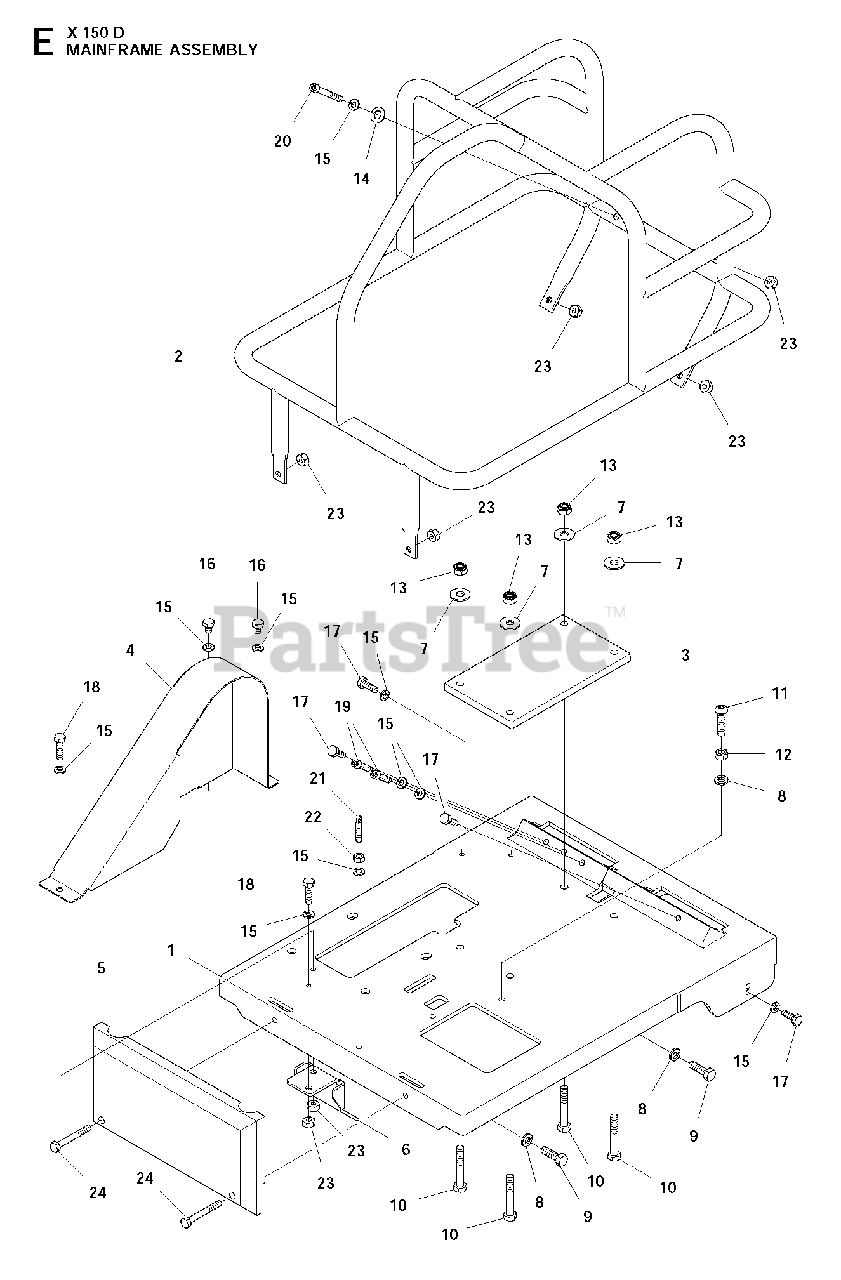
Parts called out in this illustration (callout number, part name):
7	FLAT WASH 5/16 USS ENGINE/BIG
9	HEX BOLT 5/16-18-1 CAD GR 5
13	NYLOC NUT 5/16-18 CAD PL.
23	NYLOC NUT 1/4-20 CAD PL.
